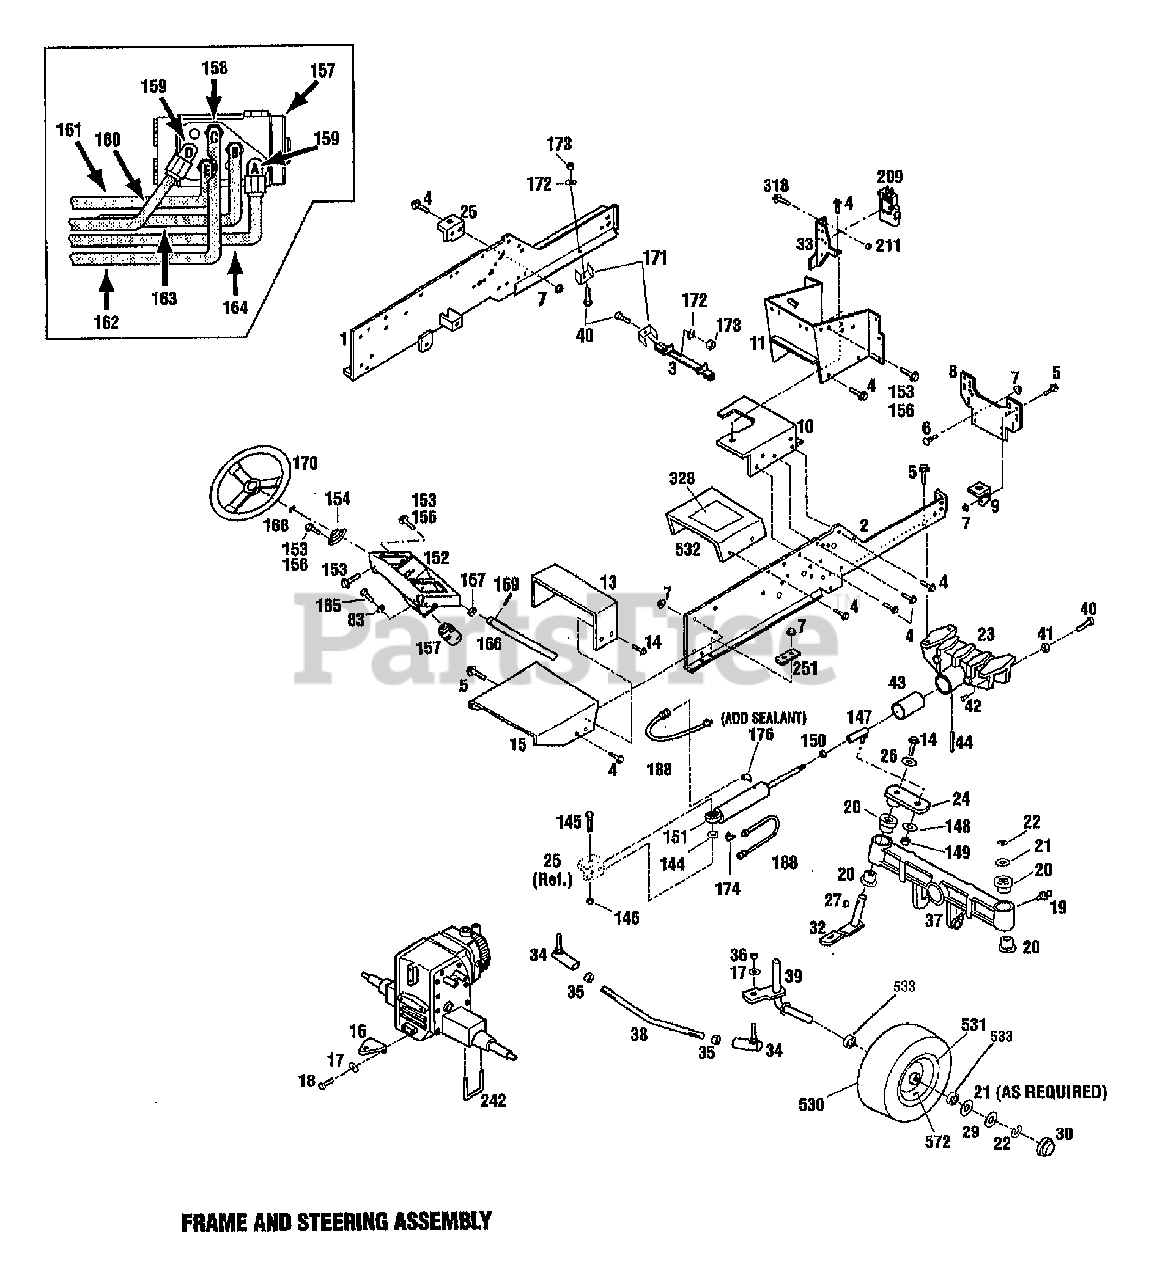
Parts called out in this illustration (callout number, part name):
3	ASSM-FRAME SUPPORT
5	SCR-HFLK 3/8-16X1.00 ZP
6	SCR-CARR 3/8-16X.75 G5 ZP
7	NUT-HFLK 3/8-16 ZP
8	PLATE-FRONT
9	SUPPORT-ENGINE
10	SUPT-BATTERY ASSM
11	SUPPORT
13	SUPPORT-FENDER
14	SCR-HFLK 5/16-18X.75 ZP
15	SUPPORT-FUEL TANK
16	HITCH-DRAWBAR
17	WASHER-LK .5
18	SCR-HH 1/2-13X1.25 G5 ZP
19	FITTING-GREASE 1/4-28X2.00
20	BEARING-FLANGE
21	WASHER-THRUST
22	RING-HEAVY EXT HD 1.0 ID
23	BOLSTER-FRONT AXLE
24	ARM-STEERING
25	BRKT-CYLINDER
26	WASHER-1.75X.328X.1345
27	KEY-WOODRUFF .25X.875
29	WASHER-SPECIAL .75X2.5
30	CAP-HUB
32	SPINDLE-WHEEL LEFT
33	SUPPORT ASSM-VALVE
34	JOINT-BALL
35	NUT-JAM
36	NUT-H/LK 1/2-20 ZP
37	AXLE-FRONT
38	ROD-TIE
39	SPINDLE-WHEEL RH
40	SCR-HH 5/16-18X1.0 G5 ZP
41	NUT-HEX JAM 5/16-18
42	PIN-WELD
43	TUBE-PIVOT AXLE
44	PIN-.312X.75
83	WASHER-LK .25 ZP
144	SLEEVE-CYLINDER
145	SCR-HH 5/8-11X3.0 G5
146	NUT-LOCK
147	JOINT-BALL
148	WASHER-LK 1.072X.634X.156
149	NUT-LK TOP 5/18-18
150	NUT-HEX/JAM 5/8-18 ZP
151	CYLINDER-HYDRAULIC
153	SCR-HFLK 5/16-18X.62 G5ZP
154	BRG-FLANGE
156	NUT-HFLK 5/16-18 ZP
157	CONTROL UNIT
158	CONNECTOR
159	ELBOW
160	TUBE-HYD RIGHT
161	TUBE-HYD PB VALVE
162	TUBE-HYDRO PRESSURE
163	TUBE-HYD LEFT
164	TUBE-HYD S C U TANK
165	SCR-HH M6-1.0X19MM
166	SHAFT-STEERING
167	COLLAR
168	RING-RET."E".577 ID
169	DRIVE PIN
170	WHEEL-STEERING & CAP
171	CLAMP
172	WASHER-LK .312 ZP
173	NUT-HEX 5/16-18 ZP
174	ELBOW
176	ELBOW
188	ASSM-HOSE
209	VALVE-HYDRAULIC
211	NUT-HF/LK 1/4-20 ZP
242	BOLT-U
251	DOUBLER-FRAME REAR
318	SCR-HH 1/4-20X.625
328	DECAL-OPERATING INST
530	TIRE-16X6.50-8
531	WHEEL
532	TUNNEL W/DECAL
533	BEARING-BALL
572	STEM-VALVE
